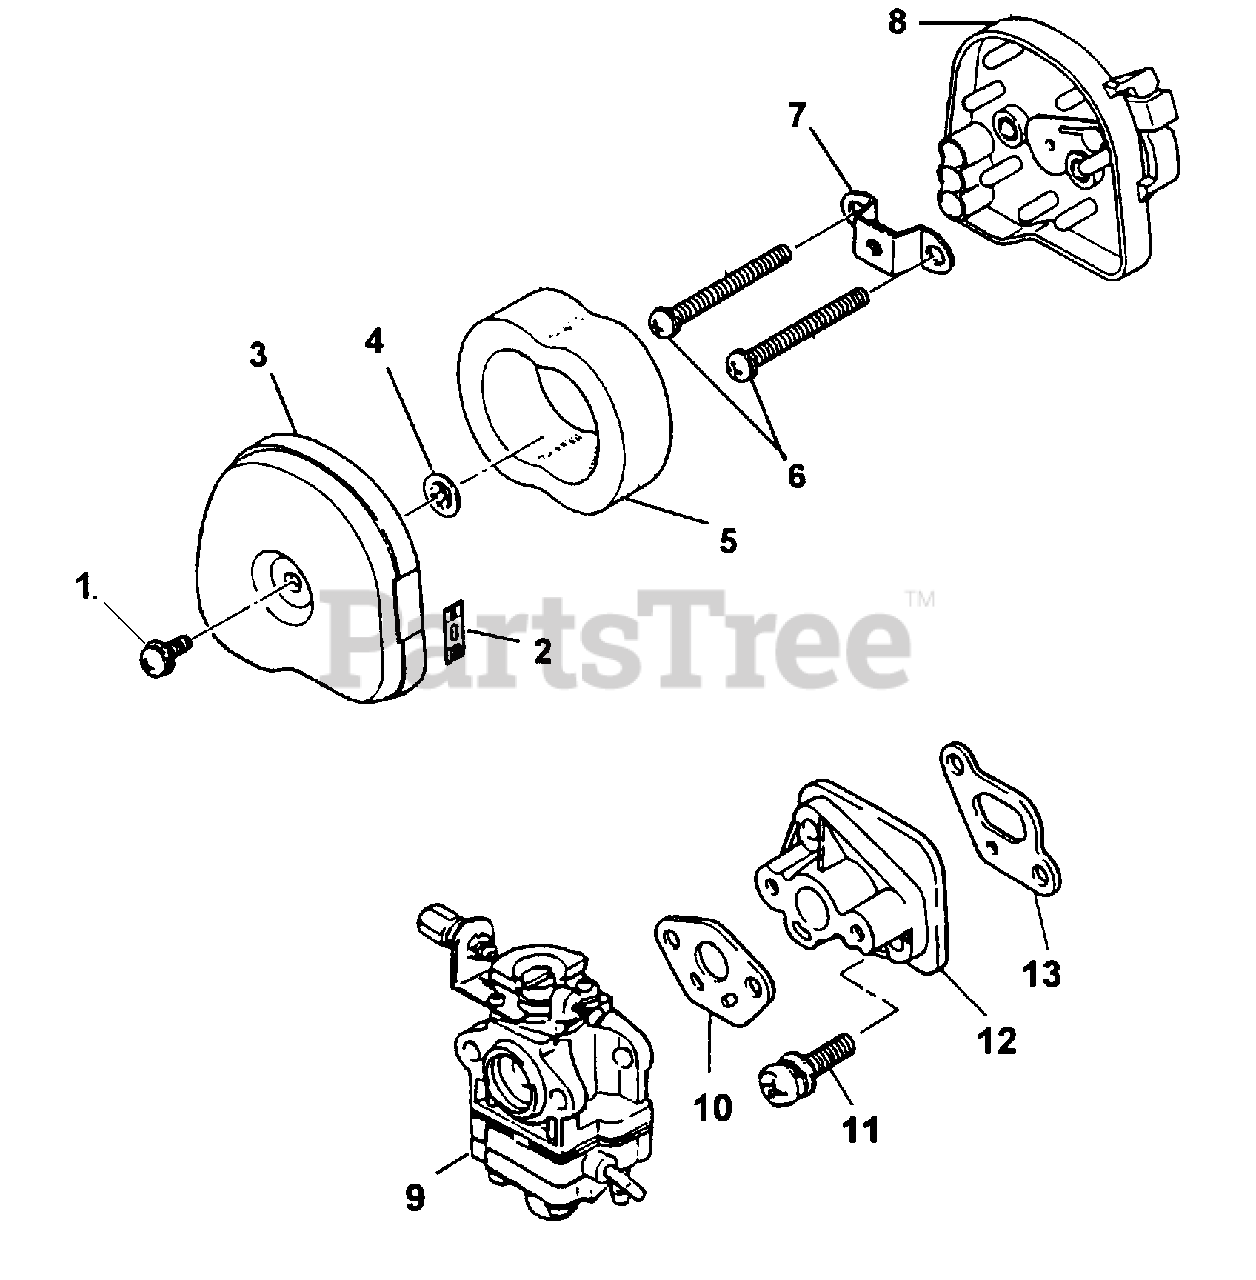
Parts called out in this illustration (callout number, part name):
1	SCREW & WASHER
2	LABEL, CHOKE
5	ELEMENT
6	SCREW & WASHER
7	BRACKET
9	CARBURETOR (23cc)
9	CARBURETOR (26cc)
10	GASKET, CARB
11	SCREW & WASHER
12	INSULATOR
13	GASKET, INSULATOR
